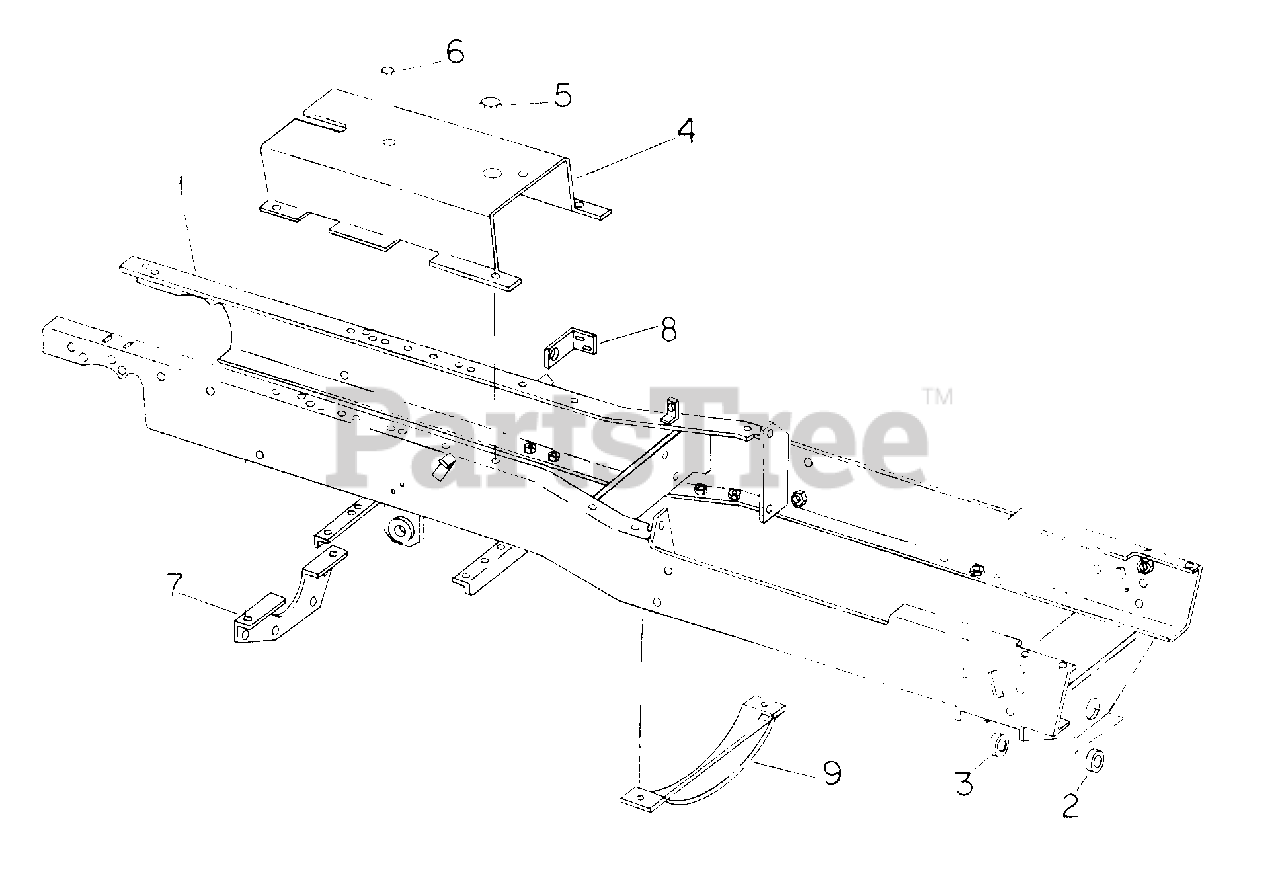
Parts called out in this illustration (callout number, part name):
2	HUB, FRONT AXLE PIVOT PIN FRONT
3	HUB, FRONT AXLE PIVOT PIN REAR
4	COVER, FRAME TOP
5	PLUG, 1-1/4 BUTTON
6	PLUG, 7/8 BUTTON
7	SUPPORT, TRANSMISSION
8	BRACKET, SWITCH
9	SHIELD ASSY, FLYWHEEL
